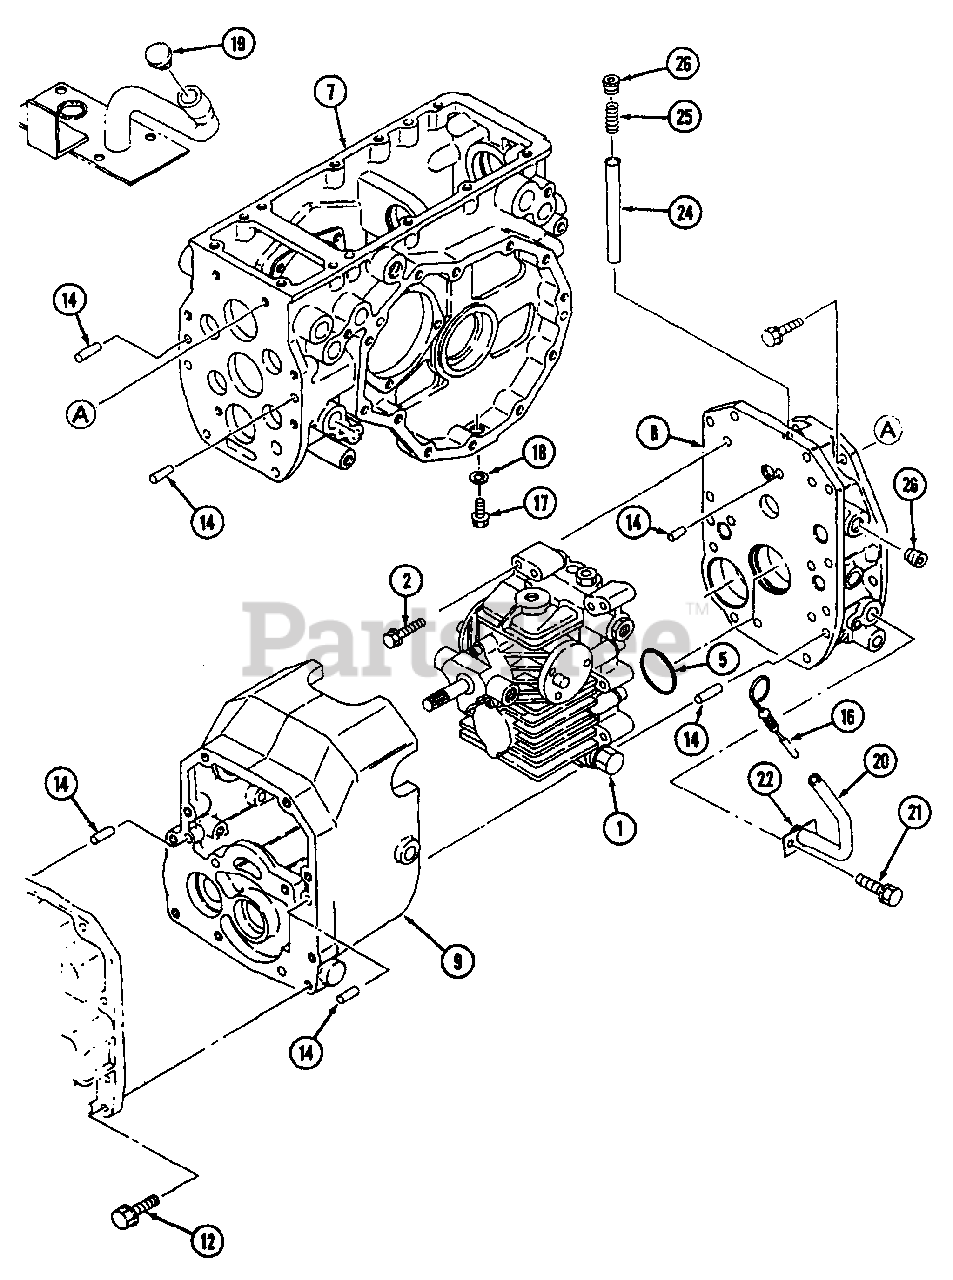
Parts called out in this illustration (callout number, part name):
1	Hydrostatic Unit
18	Seal, Washer
22	O-Ring
